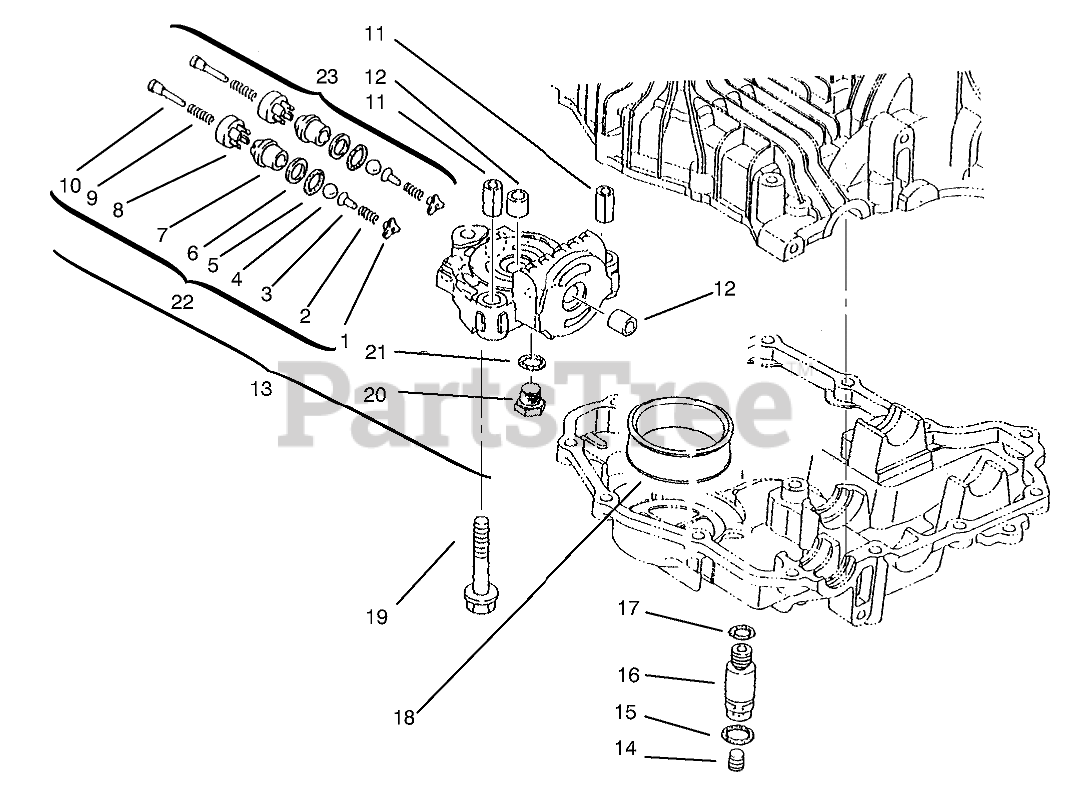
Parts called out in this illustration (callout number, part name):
1	Holder-Bypass
3	Holder-Ball
4	Ball
5	PACKING
6	RING-BACK UP
8	Valve B
10	Pin-Push
11	PIN-KNOCK
12	BUSHING
13	Case INC 11-12 & 20-23
15	PACKING
16	CONNECTOR
17	PACKING
18	FILTER
21	PACKING
22	ASM - VALVE A1 INC 1-10
23	ASM - VALVE A2
